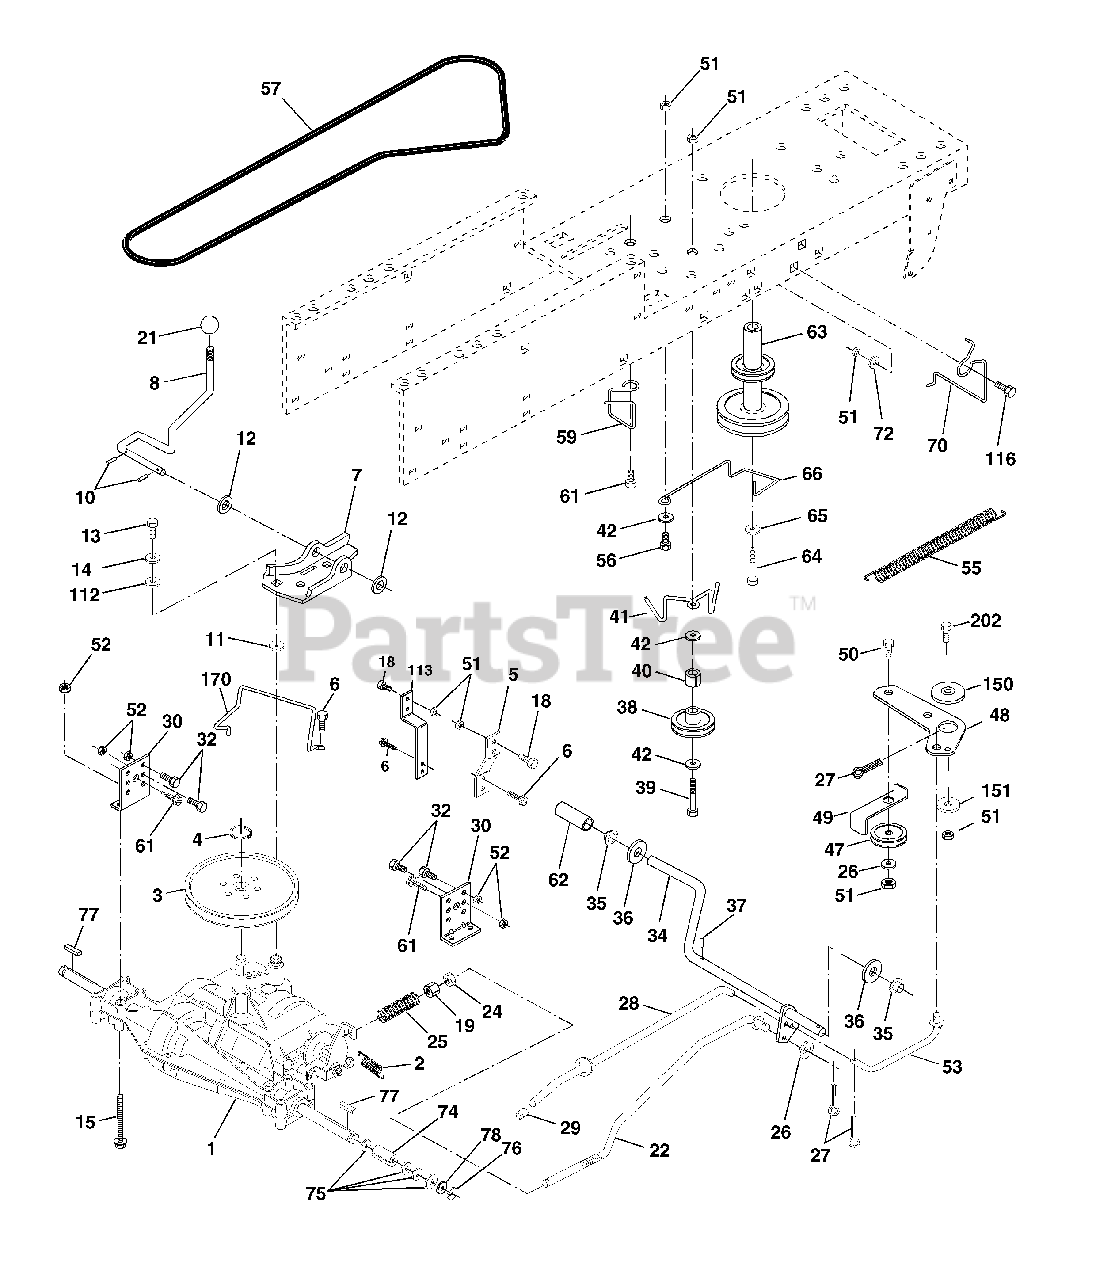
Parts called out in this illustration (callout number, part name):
2	Spring Return Brake
3	Pulley Transaxle 18" tires
4	Ring Retainer # 5100-62
5	Strap Torque 30 Degrees RH
6	Screw 5/16-18 x 3/4
7	Plate Rod Shift T/a
8	Rod Shifter Blk
10	Pin Cotter 1/8 X 1 Cad
11	Washer Plate Shf 388 Sq Hole
12	Washer 15/32 X 3/4 X 16 Ga
13	Bolt 1/4-28 unf Gr. 8 w/Patch
14	Washer Lock Hvy Helical 1/4
15	Bolt Hex Flg.Hd. 5/16-18 x Gr.5
18	Bolt Fin Hex 3/8-16unc X 1 Gr. 5
19	Nut lock Hex w/Ins 3/8-16 Unc
21	Knob Rd 1/2-13 Plstc Thds Blk
22	Rod Brake LT
24	Nut Hex Jam 3/8-16 Unc
25	Spring Rod Brake 2 00 Zinc
26	Washer 13/32 X 5/8 X 16 Ga
27	Pin Cotter 1/8 X 3/4 Cad
28	Rod Brake Parking LT/YT
29	Cap Brake Parking Black
30	Bracket Transmission
32	Bolt Fin Hex 5/16-18 x 3/4
34	Shaft Asm Pedal Foot
35	Bearing Nylon Blk 629 Id
36	Washer 21/32 X 1 X 16 Ga
37	Pin Roll 3/16 X 1"
38	Pulley Idler Flat
39	Bolt Fin Hex 3/8-16 Unc x 2-3/4
40	Spacer Split 395 X 59 Bzp
41	Keeper Belt Idler
42	Washer 13/32 X 13/16 X 12 Ga
47	Pulley Idler V Groove Plastic
48	Bellcrank Clutch Grnd Drv STL
49	Retainer Belt Style Spring
50	Bolt Hex Hd 3/8-16unc X 1-1/2
51	Nut Crownlock 3/8-16 Unc
52	Nut Crownlock 5/16-18 unc
53	Link Clutch 7 66
55	Spring Return Clutch 6 75
56	Bolt Fin Hex 3/8 X 16 x 1-1/4
57	V-Belt Ground Drive 95
59	Keeper Belt Span Ctr
61	Screw 3/8-16 x 3/4
62	Cover Pedal Blk Round
63	Engine Pulley LT/YT
64	Bolt Hex 7/16-20x4 Gr 5
65	Washer Lock Hvy Hlcl Spr 7/16
66	Keeper Belt Engine
70	Guide Belt Mower Drive RH
72	Washer 13/32 X 1-1/4 X 12 Ga
74	Spacer Axle
75	Washer 25/32 X 1 1/4 X 16 Ga
76	E-ring #5133-75
77	Key Square 2 0 X 1845/ 1865
78	Washer 25/32 X 1-5/8 X 16 Ga
112	Washer 9/32 X 3/4 X 10 Ga
113	Strap Torque 90 Degrees LH
116	Bolt Rdhd Sq Neck 3/8-16 x 1.25
150	Bushing Bellcrank
151	Washer 13/32 x 2 x 10 Ga.
170	Keeper Belt Transaxle Gear
202	Bolt Carr Sh 3/8-16 x 1-1/2 Gr.5
204	Screw 5/16-18 x 3/4
